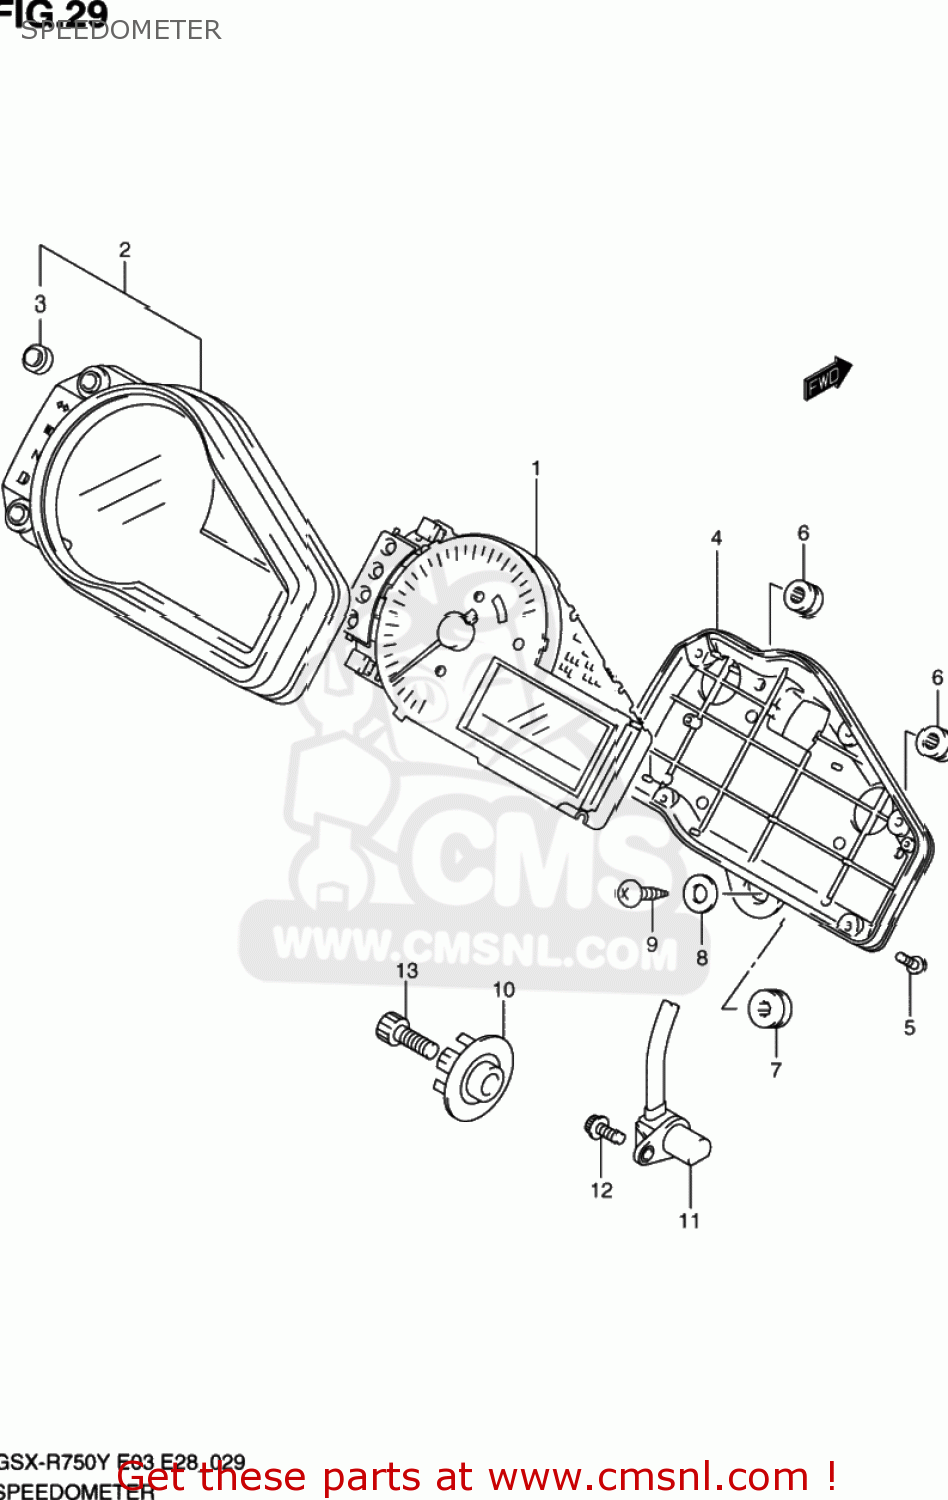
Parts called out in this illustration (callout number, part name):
1	SPEED & TACHOMETER ASSY
2	CASE,UPR
3	SWITCH,LEVER
4	CASE,LWR
5	SCREW(3X16)
6	CUSHION
7	CUSHION,METER
8	WASHER(5.5X16X1.2)
9	SCREW
10	ROTOR,SPEED
11	SENSOR,SPEED
12	BOLT
13	BOLT
